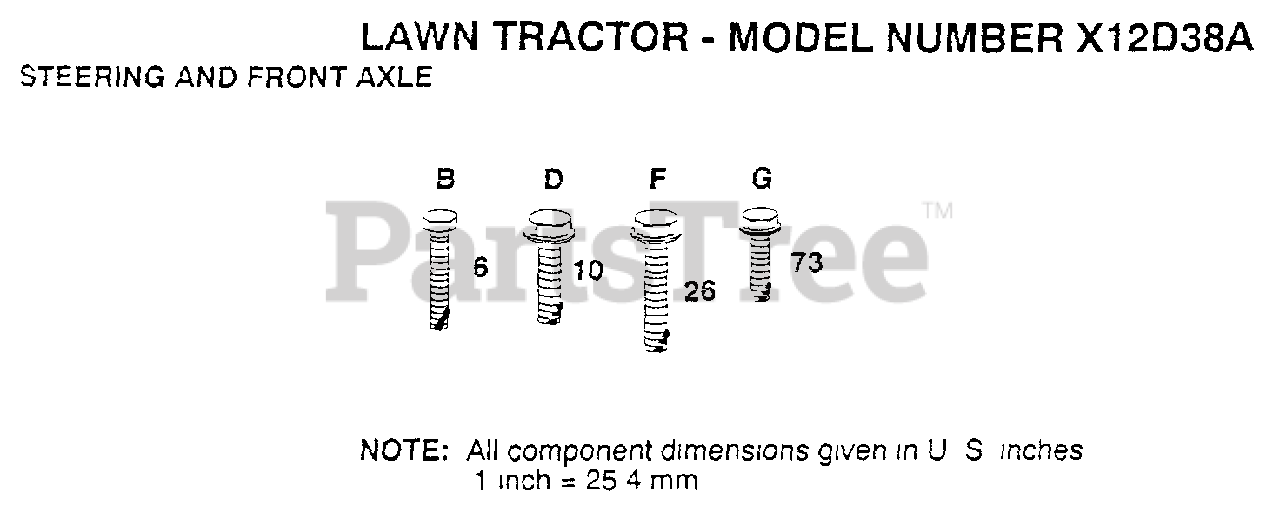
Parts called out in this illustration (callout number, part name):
6	SCREW LT
10	SCREW LT
26	SCREW
73	SCREW LT
